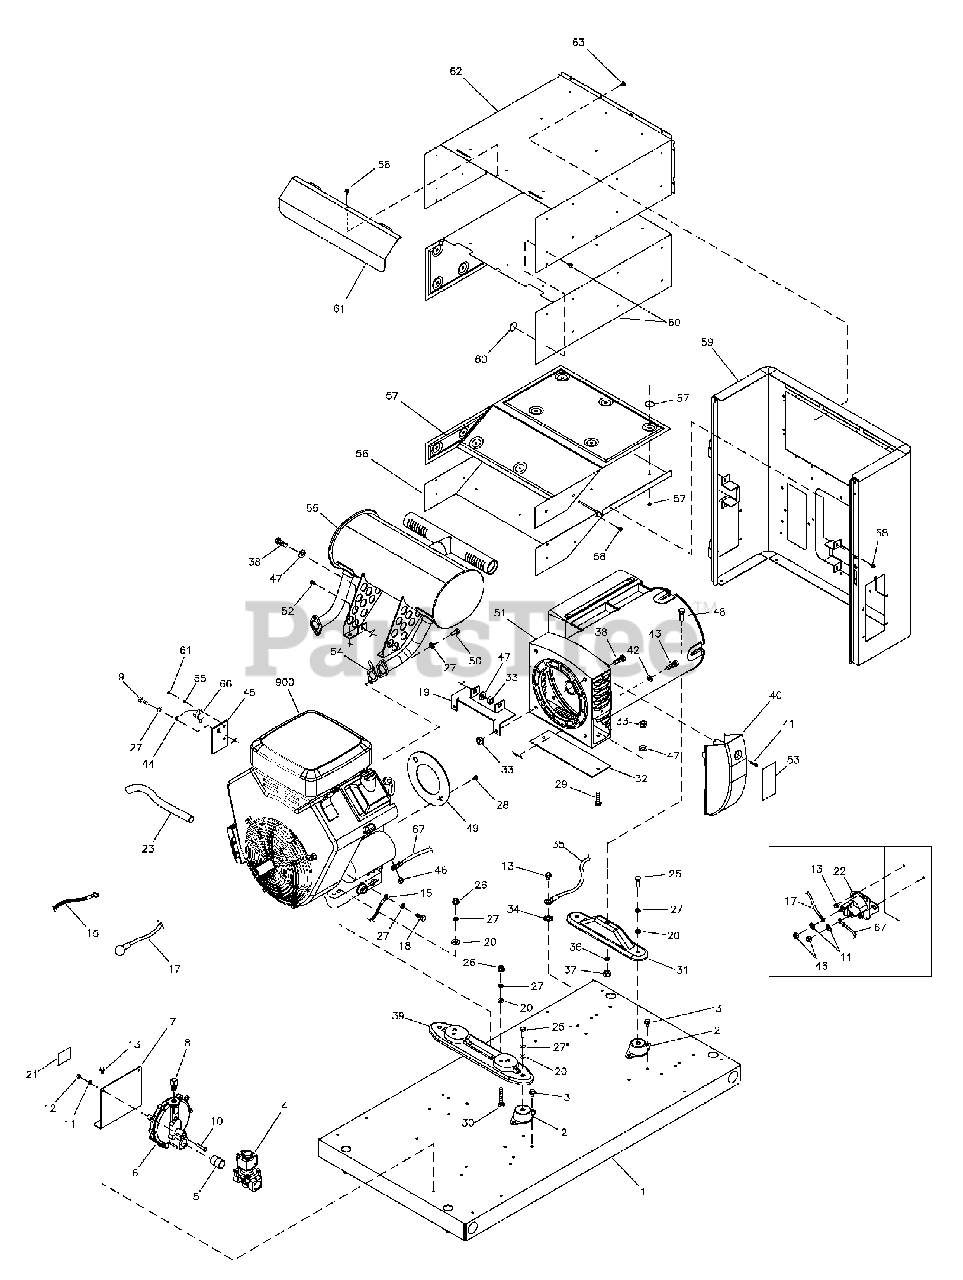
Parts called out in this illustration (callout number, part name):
1	BASE
2	MOUNT, Vibration
4	SOLENOID, Gas Fuel
6	REGULATOR, NG/LPG
7	BRACKET
9	* CAPSCREW, Hex Head, M8 - 1-1/4 x 12
10	* CAPSCREW, Hex Head, M6-1.0 x 30
11	* WASHER, Lock, 1/4
12	* NUT, M6-1
13	BOLT
15	CABLE, Battery, Black
17	CABLE, Battery, Red
18	* CAPSCREW, Hex Head, M8 - 1-1/4 x 16
20	* WASHER, Flat, 5/16-M8
22	SOLENOID / BRACKET
23	HOSE, Oil Drain
25	* CAPSCREW, Hex Head, 5/16-18 x 1
26	* NUT, 5/16-18
27	* WASHER, Lock, 5/16-M8
28	* CAPSCREW, Hex Head, 5/16-24 x 3/4
29	* CAPSCREW, Hex Head, 1/4-20 x 1
30	* CAPSCREW, Hex Head, 5/16-18 x 1-3/4
31	SUPPORT, Alternator
34	* WASHER, Shakeproof, M6-1/4
36	* WASHER, Lock, M10
37	* NUT, Hex, M10
38	* CAPSCREW, Hex Head, 1/4-20 x 3/4
39	SUPPORT, Alternator
42	* WASHER, Lock, 3/8
43	* CAPSCREW, Hex Head, 3/8-16 x 1-1/4
45	PLATE, Temp Switch
46	* NUT, Hex, 1/4-20
47	* WASHER, Flat, M6
48	* CAPSCREW, Hex Head, M10 - 1-1/2
51	ALTERNATOR
59	BULKHEAD, Alternator
62	BOX, Muffler Top
64	* SCREW, Phillips Head, 4-40 x 0.19
65	* WASHER, Lock, #4
900	** ENGINE
